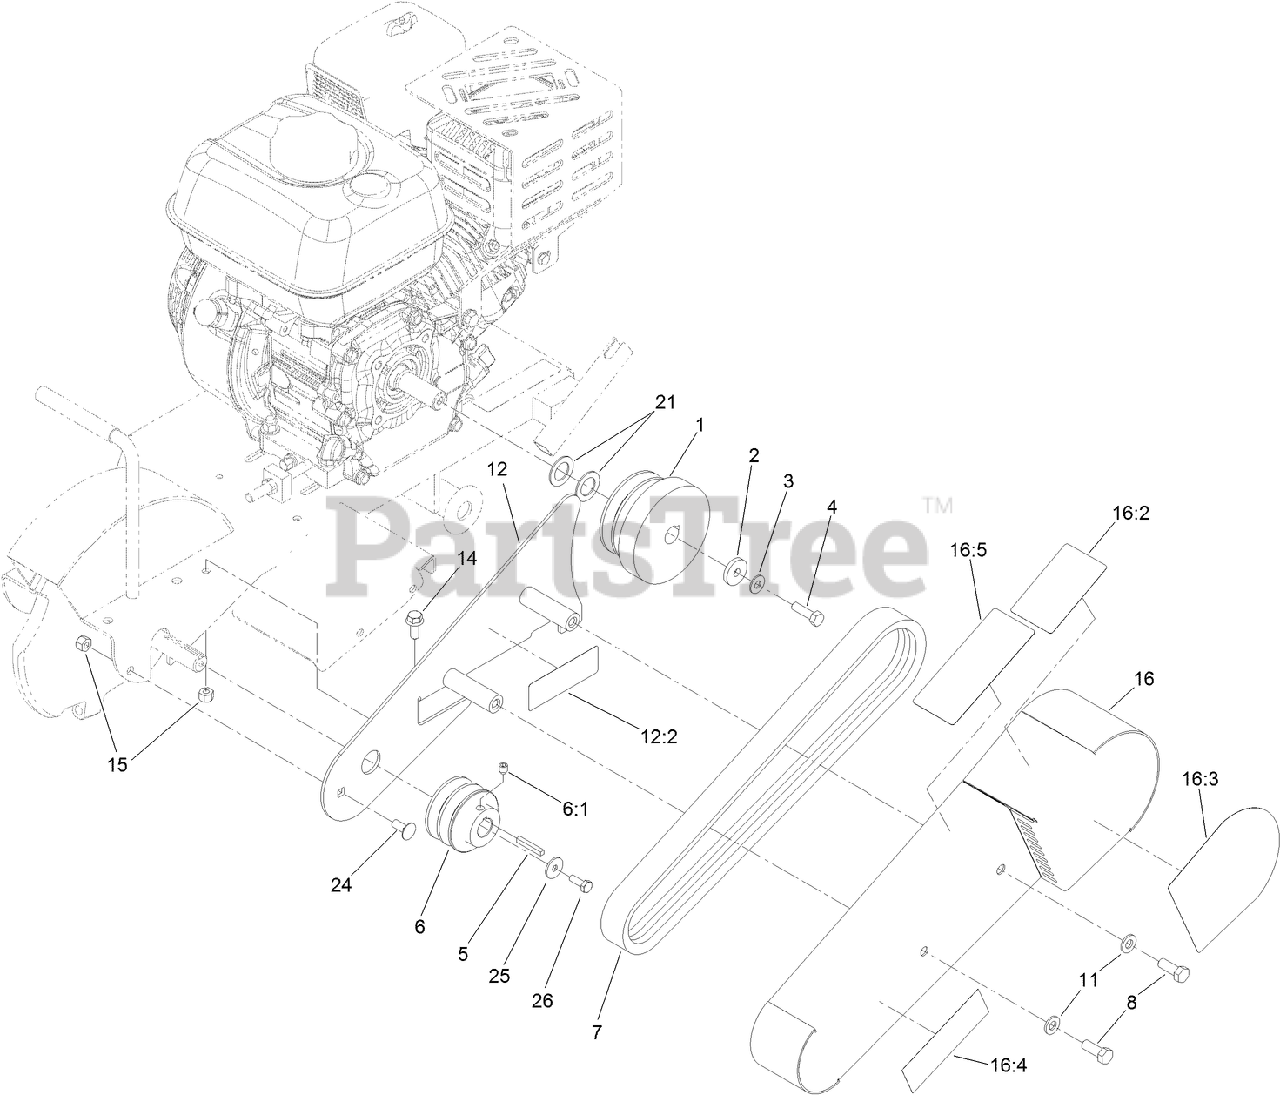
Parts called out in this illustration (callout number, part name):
1	CLUTCH-CENTRIFUGAL
2	WASHER-HARDENED
3	WASHER-FLAT
4	SCREW-HH
5	KEY-SQUARE
6	PULLEY-FRONT
6:1	SCREW-HSH
7	BELT-V, BANDED
8	SCREW-HH
11	WASHER-FLAT
12	PLATE-GUARD, INNER
12:2	DECAL-WARNING
14	SCREW-HHF
15	NUT-LOCK, NI
16	BELT GUARD ASM
16:2	DECAL-CAUTION
16:5	DECAL-SERVICE
21	WASHER-THRUST
24	SCREW-CARR
25	WASHER
26	SCREW-HH
